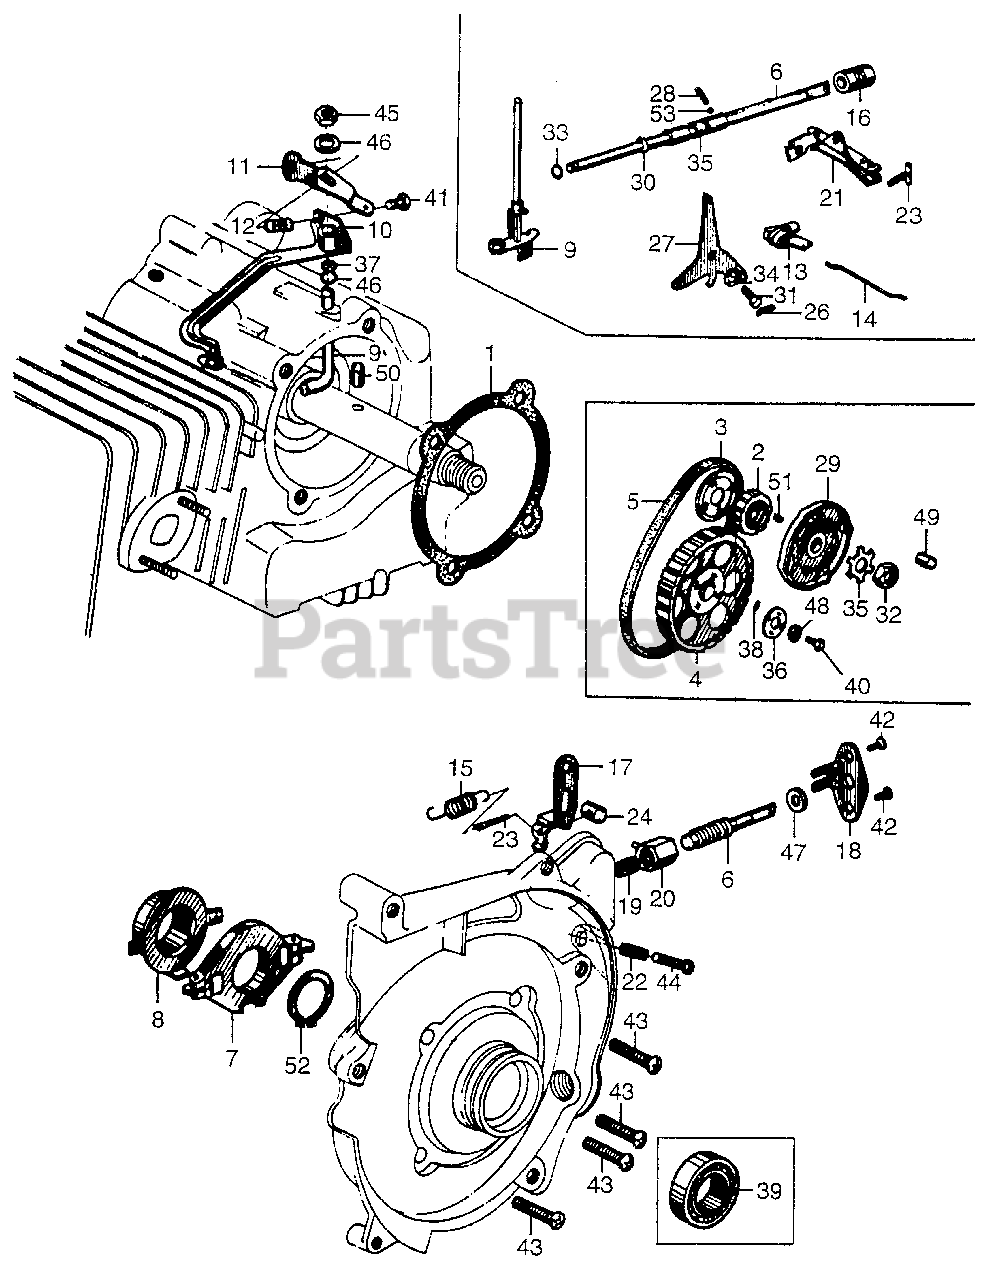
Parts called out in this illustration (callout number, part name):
2	PULLEY, TIMING (NOT AVAILABLE)
3	PLATE, TIMING PULLEY SIDE (NOT AVAILABLE)
4	PULLEY, CAM (NOT AVAILABLE)
5	BELT, TIMING (NOT AVAILABLE)
6	SHAFT, THROTTLE (NOT AVAILABLE)
6	SHAFT, THROTTLE
9	SHAFT, ARM (NOT AVAILABLE)
10	ARM, GOVERNOR (NOT AVAILABLE)
13	ARM, SPRING (NOT AVAILABLE)
14	ROD, GOVERNOR
15	SPRING, GOVERNOR (NOT AVAILABLE)
16	SCREW, GOVERNOR CONTROL
21	LEVER, GOVERNOR SPRING (NOT AVAILABLE)
23	SCREW, ADJUSTING (NOT AVAILABLE)
23	SCREW, ADJUSTER
26	SPRING, LOCK (3.6MM) (NOT AVAILABLE)
27	LEVER, CHOKE
28	SPRING, CHOKE ADJUSTING
29	HOLDER, STARTER PAWL (NOT AVAILABLE)
30	RING, SNAP (3.2MM) (NOT AVAILABLE)
31	BOLT, SPECIAL (5MM) (NOT AVAILABLE)
32	NUT, SPECIAL (12MM) (NOT AVAILABLE)
33	O-RING (4MM) (NOT AVAILABLE)
34	WASHER, SPECIAL (7MM)
35	GUIDE, CHOKE ADJUSTING (NOT AVAILABLE)
35	WASHER, LOCK (12MM)
36	WASHER, SPECIAL (5MM) (NOT AVAILABLE)
38	PIN, KNOCK (4MM) (NOT AVAILABLE)
39	BEARING, BALL (609UU) (NOT AVAILABLE)
40	BOLT, HEX. (5X14)
48	WASHER, SPRING (5MM)
49	PIN, DOWEL (7X12)
51	KEY, WOODRUFF (16X12)
53	BALL, STEEL (#5) (5/32)
